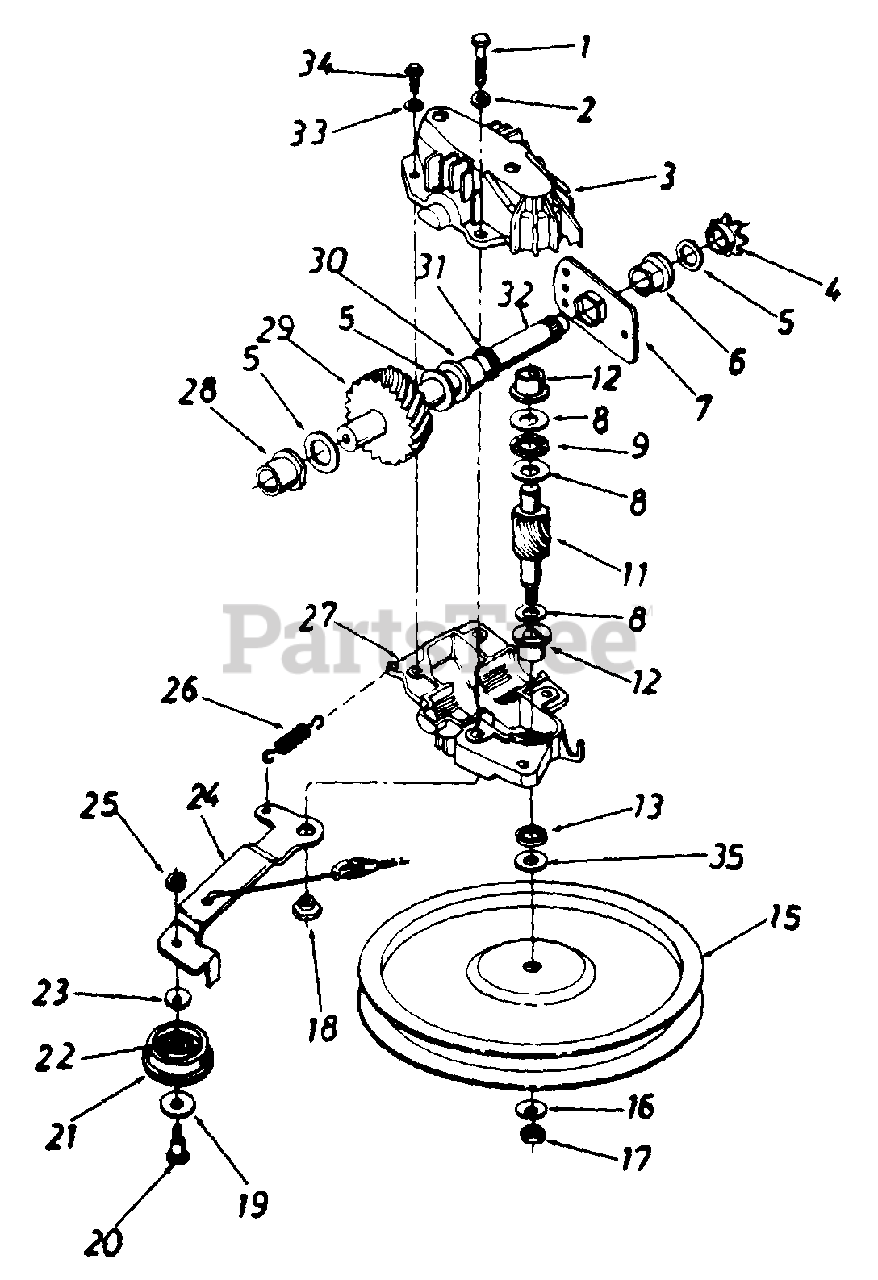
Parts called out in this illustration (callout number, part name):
1	Hex Bolt 1/4-20 x 1.25" Lg. w/Patch
2	L-Wash. 1/4" I.D.
3	Upper Hsg. Half
4	#48 Sprocket 7 Tooth x 1/2 Pitch
5	Fl-Wash. 5/8" I.D. x .030
6	Hex Flange Brg..631" I.D.
8	Thrust Wash..382" I.D. x .70" O.D.
9	Thrust Bearing .375" I.D. x .812" O.D.
11	11 Tooth Pinion Shaft
12	Flange Bearing
13	Oil Seal
15	Fl-Pulley 5.06" O.D.
16	Bell-Wash..265" I.D. x.75"
17	Hex L-Nut 1/4-28 L.H. Thd.
18	Shld. Spacer .375" Dia. x .170
19	Fl-Wash..390" I.D. x 1.0"
20	Shld. Bolt .375" Dia. x .40"
21	Fl-Idler Plastic 1.50" Dia.
22	Needle Brg..375" x .31
23	Bell-Wash. .265" I.D. x .75"
24	Idler Brk't. Ass'y.
25	Hex Patch L-Nut 1/4-28 Thd.
26	Extension Spring 1.12" Lg.
27	Lower Hsg. Half
28	Flange Bearing .566 Dia.
29	33 Tooth Helical Gear
30	Flange Bearing .629 Dia.
31	Oil Seal .625 Dia.
32	Gear Sprocket Shaft
33	L-Wash. #10 I.D.
34	Hex 8-Tap Scr. #10 x .62"
35	Hex Washer .26" x .88"
